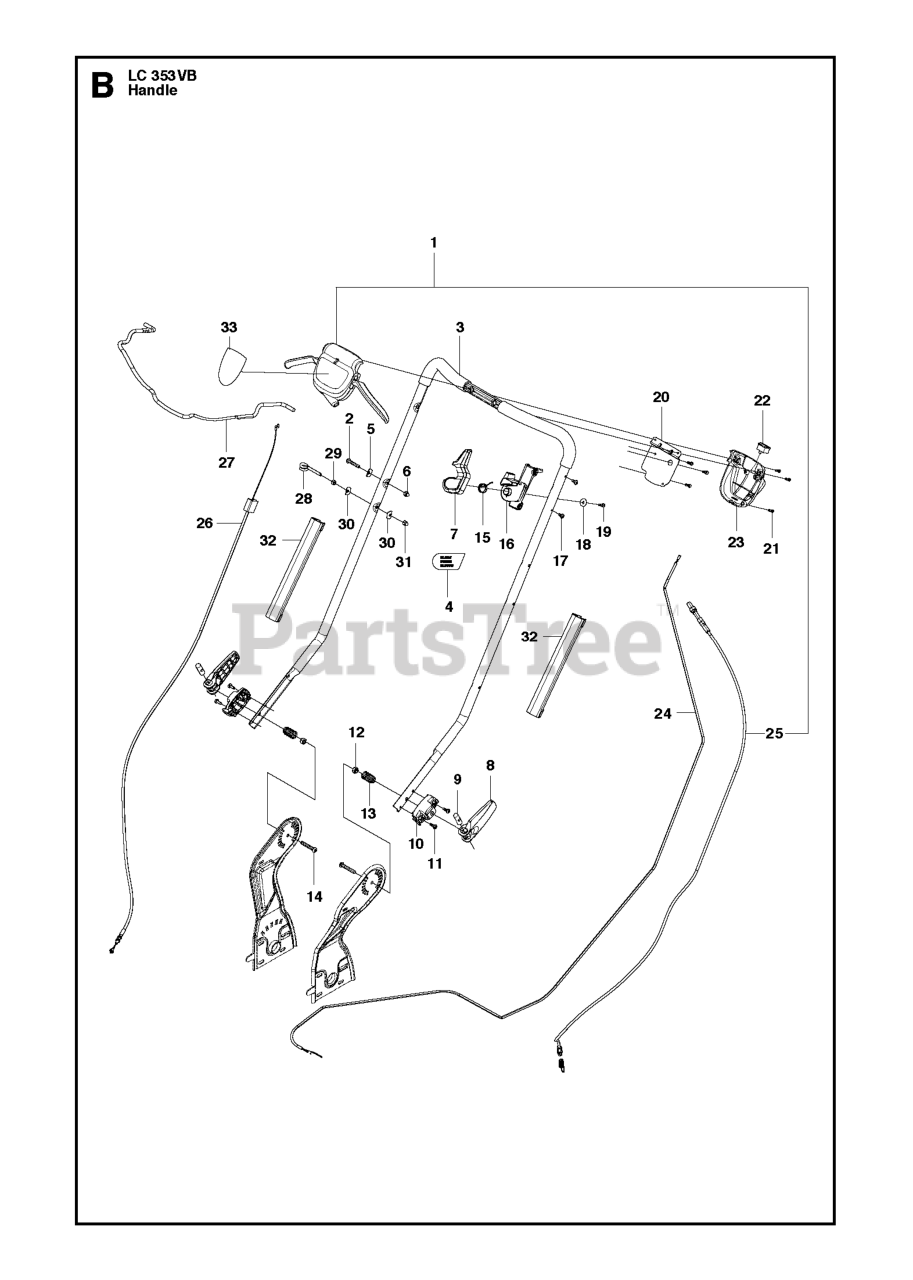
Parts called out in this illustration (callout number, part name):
12	LOCKNUT M8
17	SCREW ITXPANTT M5X10 ZPB (A00
18	WASHER - 26X6.5X1.6
